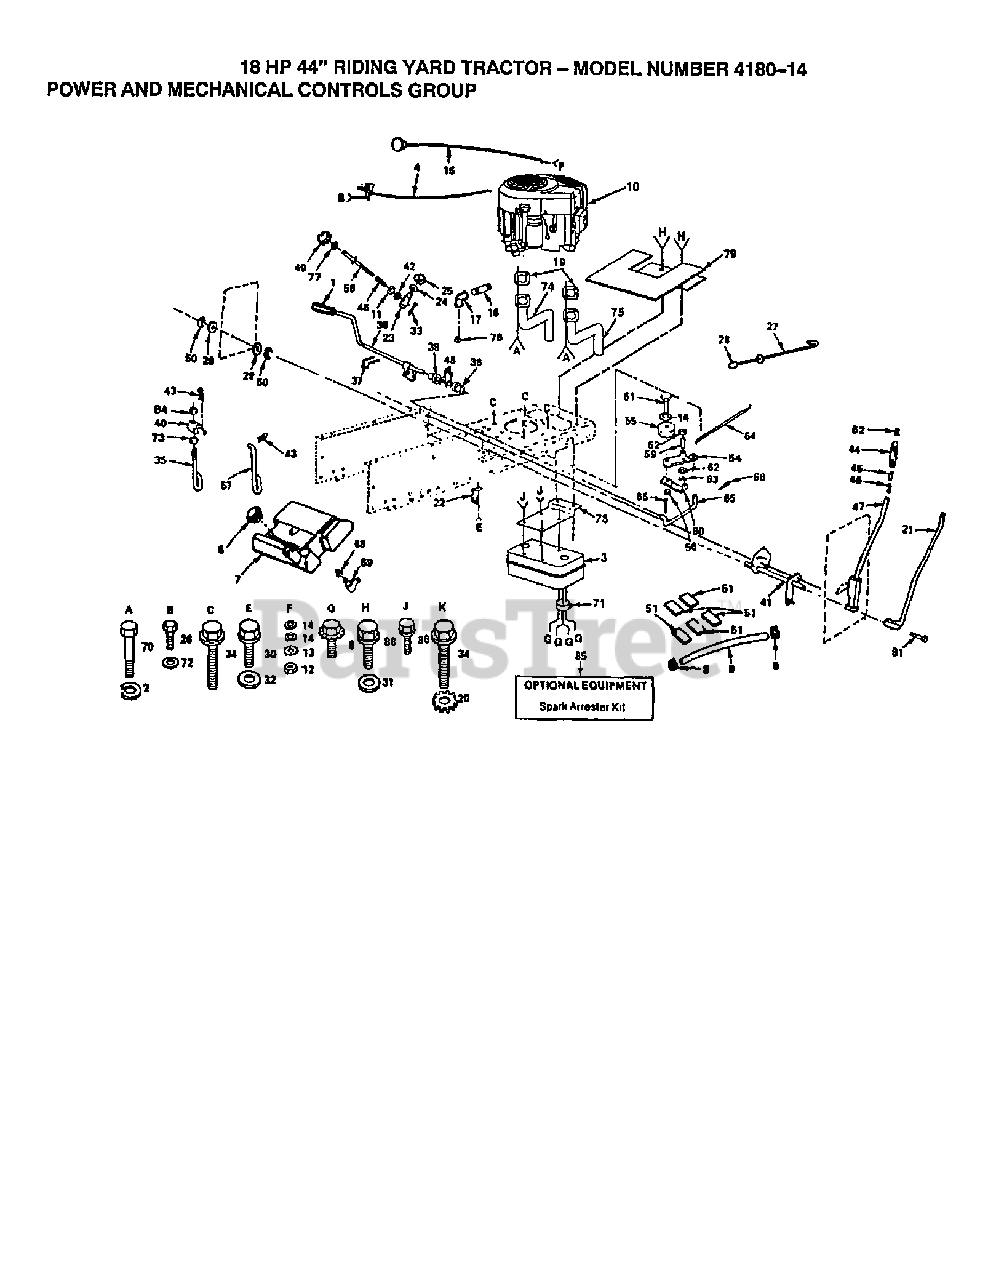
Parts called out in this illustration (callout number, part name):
1	PEDAL COVER
2	LOCKWASHER
6	SCREW LT
8	HOSE CLAMP
9	FUEL LINE T
11	WASHER
12	NUT
13	LOCKWASHER
15	CONTROL CHOKE
16	NIPPLE, PIPE 3/8NPT X 4-1/2
17	ELBOW
19	Poulan TBD
20	LOCKWASHER
21	LEVER ROD LT
22	BELT RETAINER
23	TRUNION LT
24	WASHER
25	KLIP RING
27	ROD BRAKE PARK
28	PLUNGER CAP
35	LINK ADJ T
37	Drive Pin, 3/16 X 1"
38	BEARING.NYLON
40	TRUNNION T
43	RETAINER SPRING
44	GRIP
45	PLUNGER BUT KIT
47	LIFT LEVER KIT
48	WASHER LT
49	HDLE ADJ LIFT
51	PAD-SPACER LT
52	PLUNGER BUT KIT
56	LOCKNUT
57	LIFT LINK LT
58	ROD LIFT LT
59	Poulan TBD
60	RETAIN BELT
61	Hex Bolt
62	WASHER LT
63	KLIP RING
64	SPRING, RETURN LT
66	COTTER PIN
68	BUSHING OUTLET T
69	FUEL TANK STEM GT
71	DEFL MUFFLER LTV
77	NUT
79	HEAT SHIELD
81	Hex Bolt
84	NUT LOCK YTH
85	SPARK ARREST
86	SCREW ST
